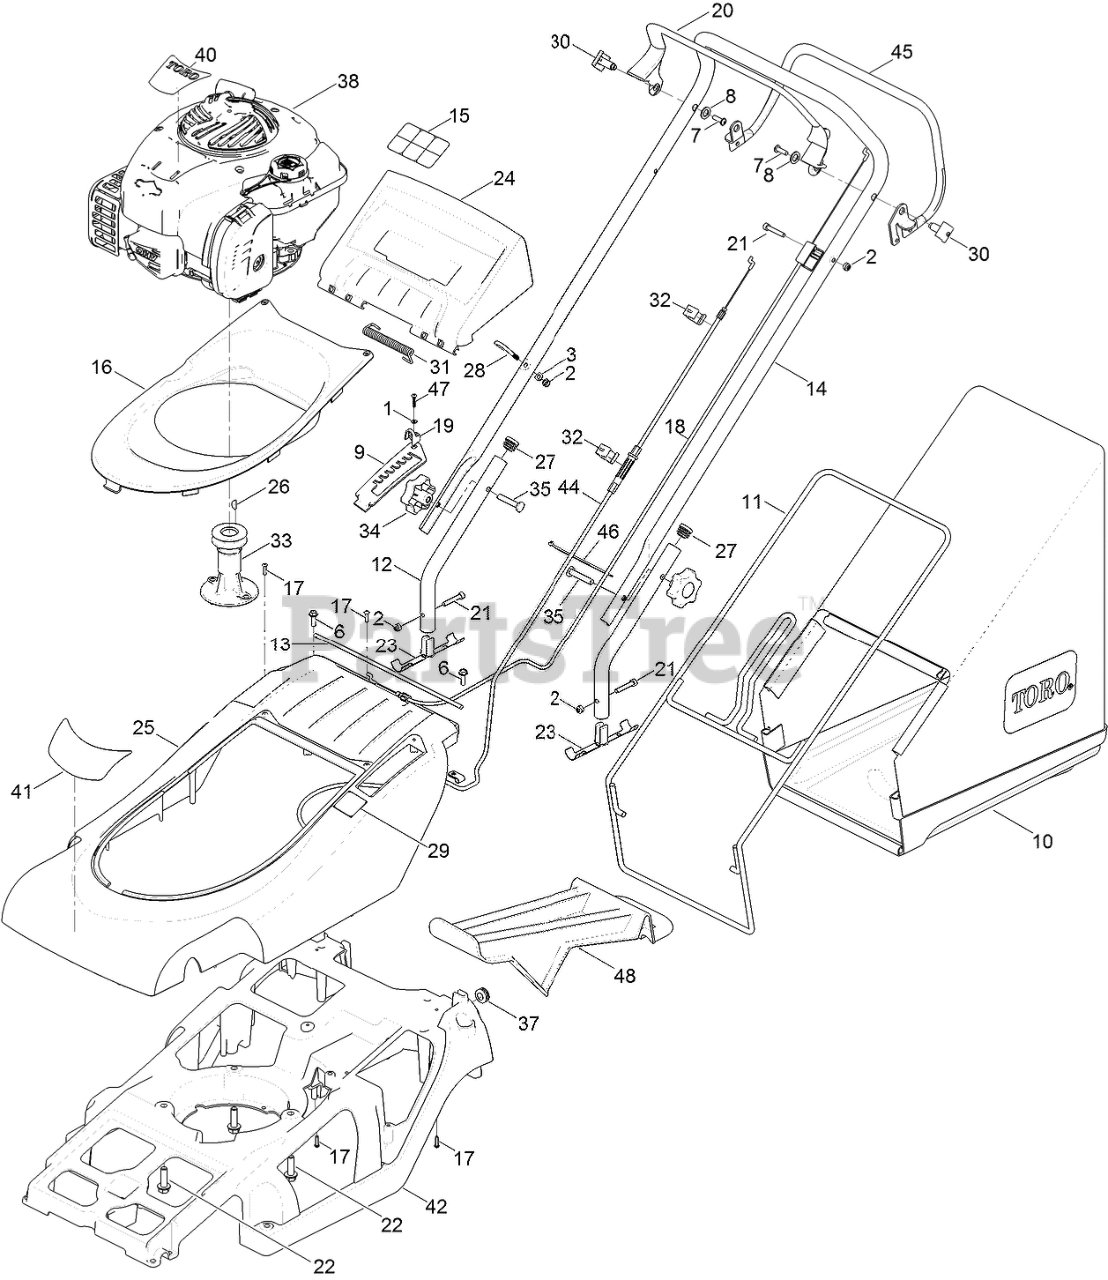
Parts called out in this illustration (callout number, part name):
1	WASHER
2	NUT-NYLOC
3	WASHER-PLAIN
6	SCREW-TAPTITE
7	SCREW
8	WASHER-NYLON
9	PLATE-HOC
10	GRASSBAG
11	FRAME-GRASSBAG
12	HANDLEBARS-LOWER
13	BAR-HINGE
14	HANDLEBARS
15	DECAL-SAFETY
16	MOULDING-TRIM
18	CABLE-BRAKE, ENGINE
19	CLIP-P
20	BAILARM
21	SCREW-SOCKET
22	SCREW-TAPTITE, UNC
23	PLUG-HANDLEBAR
24	MOULDING-DEFLECTOR, REAR
25	TOP-COVER
26	KEY-WOODRUFF
27	PLUG-TUBE
28	GUIDE-ROPE
29	DECAL-HOC
30	PIN-PIVOT
31	SPRING-DEFLECTOR
32	GUIDE-CABLE
33	CARRIER-BLADE
34	KNOB-HANDLEBAR
35	BOLT-HANDLEBAR
37	GROMMET-RUBBER
40	DECAL-ENGINE
41	DECAL-RECYCLE
44	CABLE-CLUTCH, AUTO-DRIVE
45	LEVER-CLUTCH
46	TIE-CABLE
47	SCREW-PLASTITE
48	PLUG-MULCHING
